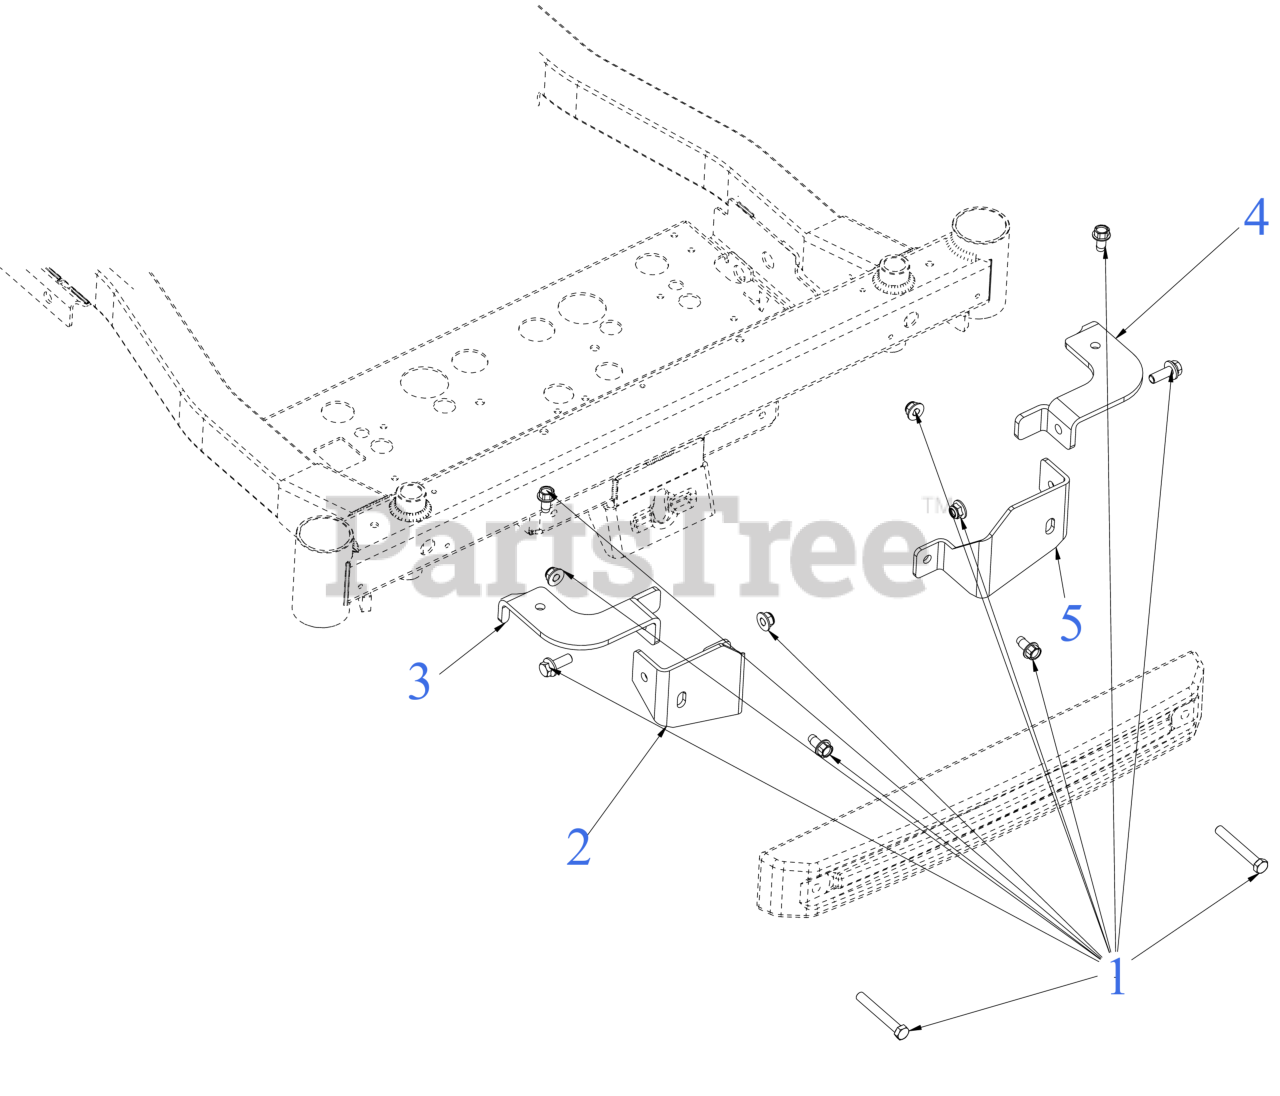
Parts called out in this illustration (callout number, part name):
1	HEX SCREW 3/8-16
1	SCREW 3/8-16 x 2.75 GR5
1	SCREW 3/8-16 x 3/4
2	MOUNTING BRACKET (LOWER) (RH)
3	MOUNTING BRACKET (UPPER) (RH)
4	MOUNTING BRACKET (UPPER) (LH)
5	MOUNTING BRACKET (LOWER) (LH)
